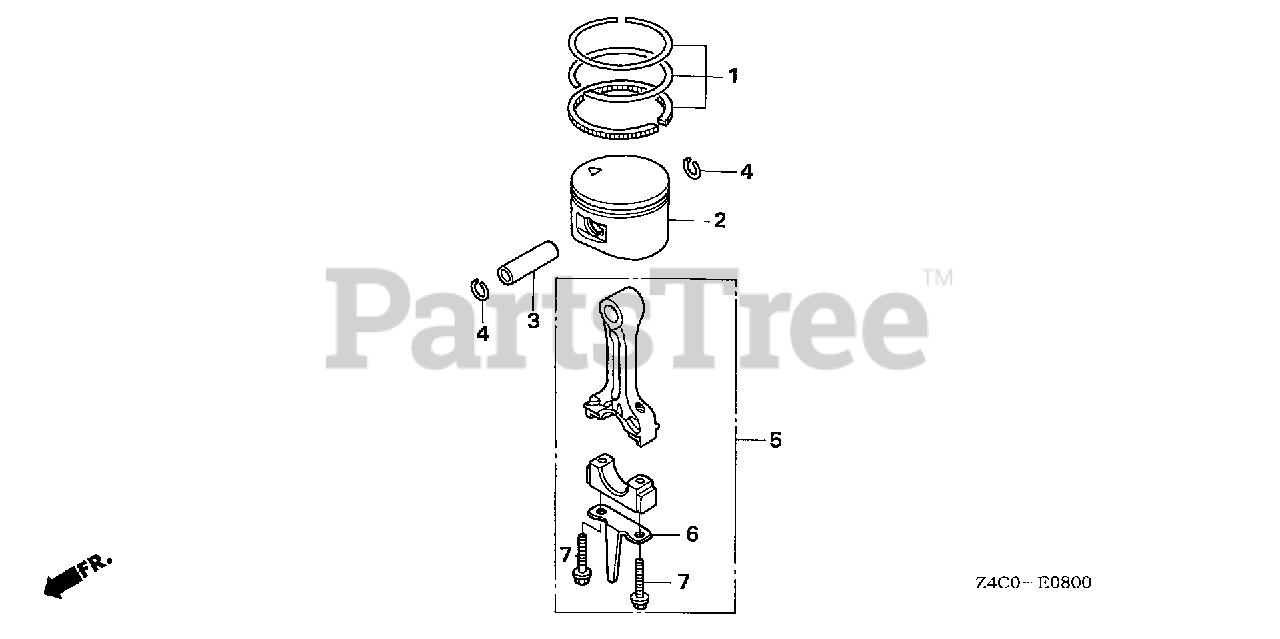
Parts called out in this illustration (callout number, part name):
1	RING SET, PISTON (STD)
2	PISTON (STD)
3	PIN, PISTON
4	CLIP, PISTON PIN (10MM)
5	ROD ASSY., CONNECTING
6	DIPPER, CONNECTING ROD
7	BOLT, CONNECTING ROD
